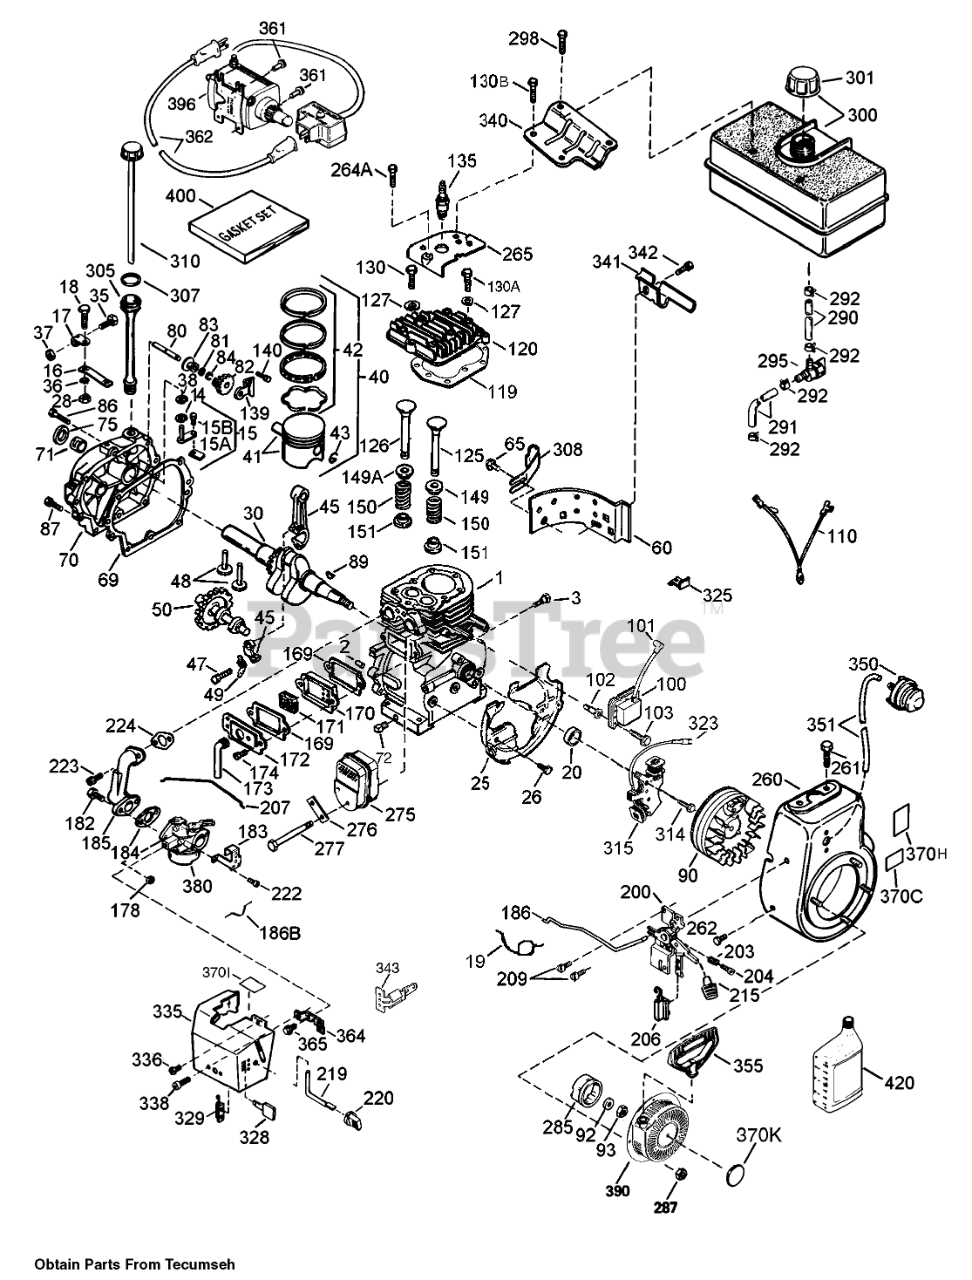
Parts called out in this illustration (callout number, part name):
1	Cylinder Asm (Incl. Ref. #2, 20, & 72)
2	Pin-Dowel
3	Screw (1/4-20x1/2)
14	Washer-Flat
15	Governor (Incl. Ref. #15A & 15B)
15A	Yoke-Governor
15B	Screw (6-40x5/16)
16	Lever-Governor
17	Clamp-Lever, Governor
18	Screw (T-15, 8-32x7/16)
19	Spring-Throttle
20	Seal-Oil
25	Baffle-Housing, Blower
26	Screw (1/4-20x19/32)
28	Nut-Lock
30	Crankshaft
35	Screw
36	Washer-Lock
37	Nut-Lock
38	Ring-Retaining
40	Piston-Pin and Ring Set (STD)
40	Piston- Pin and Ring Set (.010 O S)
41	Piston & Pin Asm (Std.)(Incl. Ref. #43)
41	Piston & Pin Asm (.010" OS)(Incl. Ref. #43)
42	Ring Set (STD)
42	Ring Set (.010 O S)
43	Ring-Retaining, Piston Pin
45	Connecting Rod Asm (Incl. Ref. #47, & 49)
47	Bolt-Rod, Connecting
48	Lifter-Valve
49	Dipper-Oil
50	Camshaft (MCR)
60	Extension-Housing, Blower
65	Screw
69	Gasket-Cover, Cylinder
70	Cylinder Cover (Incl. Ref. #71, 75, & 80)
71	Bushing-Crankshaft
72	Plug-Drain, Oil (SQH 1/4-18)
75	Seal-Oil
80	Shaft-Governor
81	Washer-Flat
82	Governor Gear Asm (Incl. Ref. #81)
83	Spool-Governor
84	Ring-Retaining
86	Screw (1/4-20x1-3/16)
87	Screw (1/4-20x1-11/16)
89	Key-Flywheel
90	Flywheel ASM
92	Washer-Belleville
93	Nut-Flywheel
100	Solid State ASM
101	Cover-Spark Plug
102	Stud-Mounting, Solid State
103	Screw (T-15, 10-24 x 15/16)
110	Wire-Ground
110A	Wire-Ground
119	Gasket-Head, Cylinder
120	Head-Cylinder
125	Exhaust Valve (Std.)(Incl. Ref. #151)
125	Exhaust valve (1/32" OS)(Incl. Ref. #151)
126	Intake Valve (Std.)(Incl. Ref. #151)
126	Intake Valve (1/32" OS)(Incl. Ref. #151)
127	Washer-Flat
130	Screw (5/16-18x1-1/2)
130A	Screw (5/16-18x1-25/32)
130B	Screw (5/16-18x39/64)
135	Spark Plug-Resistor (R J19 L M)
139	Bracket-Gear, Governor
140	Screw (10-24x1/2)
149	Cap-Spring, Valve
149A	Cap-Spring, Valve
150	Spring-Valve
151	Keeper-Spring, Valve
169	Gasket-Cover, Valve
170	Body-Breather
171	Element-Breather
172	Cover-Valve
173	Tube-Breather
174	Screw
178	Nut and Lock Washer (1/4-28)
182	Screw (1/4-28x1)
183	Bracket-Choke
184	Gasket-Carburetor To Intake Pipe
185	Pipe-Intake
186	Link-Governor
186B	Spring-Choke
200	Control Bracket (Incl. Ref.#19, 203, 204 & 206)
203	Spring-Compression
204	Screw (T-10, 5-40x7/16)
206	Terminal
207	Link-Throttle
209	Screw (10-32 x 1/2)
215	Knob-Control
219	Rod-Choke
220	Knob-Control
222	Screw (10-32 x 1/2)
223	Screw (T-30, 5/16-18x1-3/32)
224	Gasket-Pipe, Intake
260	Housing-Blower
261	Screw (5/16-18x3/4)
262	Screw
264A	Screw (1/2-20x5/8)
265	Cover-Cylinder Head
275	Muffler
276	Plate-Locking
277	Screw (5/16-18x4-3/16)
285	Cup-Starter
287	Nut and Lock Washer (1/4-28)
290	Line-Fuel (8.62)
291	Line-Fuel
292	Clamp-Line, Fuel
295	Valve-Shut Off, Fuel
298	Screw (1/4-15x7/8)
300	Fuel Tank (Incl. Ref. #292 & 301)
301	Cap-Fuel
305	Tube-Fill, Oil
307	O-Ring
308	Knob-Control
310	Gauge Oil ASM
314	Screw (1/4-20 x 3/4)
315	Alternator Coil (18 Watt)(Incl. Ref. #323)
323	Terminal
325	Clip-Wire
328	Key-Ignition
329	Terminal
335	Cover-Carburetor
336	Screw (10-32x1/2)
338	Screw (10-32 x 3/8)
340	Bracket-Tank, Fuel (Black)
341	Bracket-Tank, Fuel
342	Screw (1/4-20x19/32)
343	Bracket-Switch, Key
350	Primer ASM
351	Line-Primer
355	Handle-Starter, Mitten Grip
361	Screw (T-30, 1/4-20x15/32)
362	Cord-Extension (10-6)
364	Bracket-Carburetor
365	Screw (8-32x27/64)
370C	Decal-Primer, International Symbol
370H	Decal-Speed Control and Choke
370I	Decal-Warning (Bilingual)
370K	Decal-Tecumseh Logo for Top of Recoil Starter
380	Carburetor (Incl. Ref. #184)
390	Starter-Rewind
396	Starter-Electric (110 Volt)
400	Gasket Set
420	Oil-Engine, S A E 5W30
